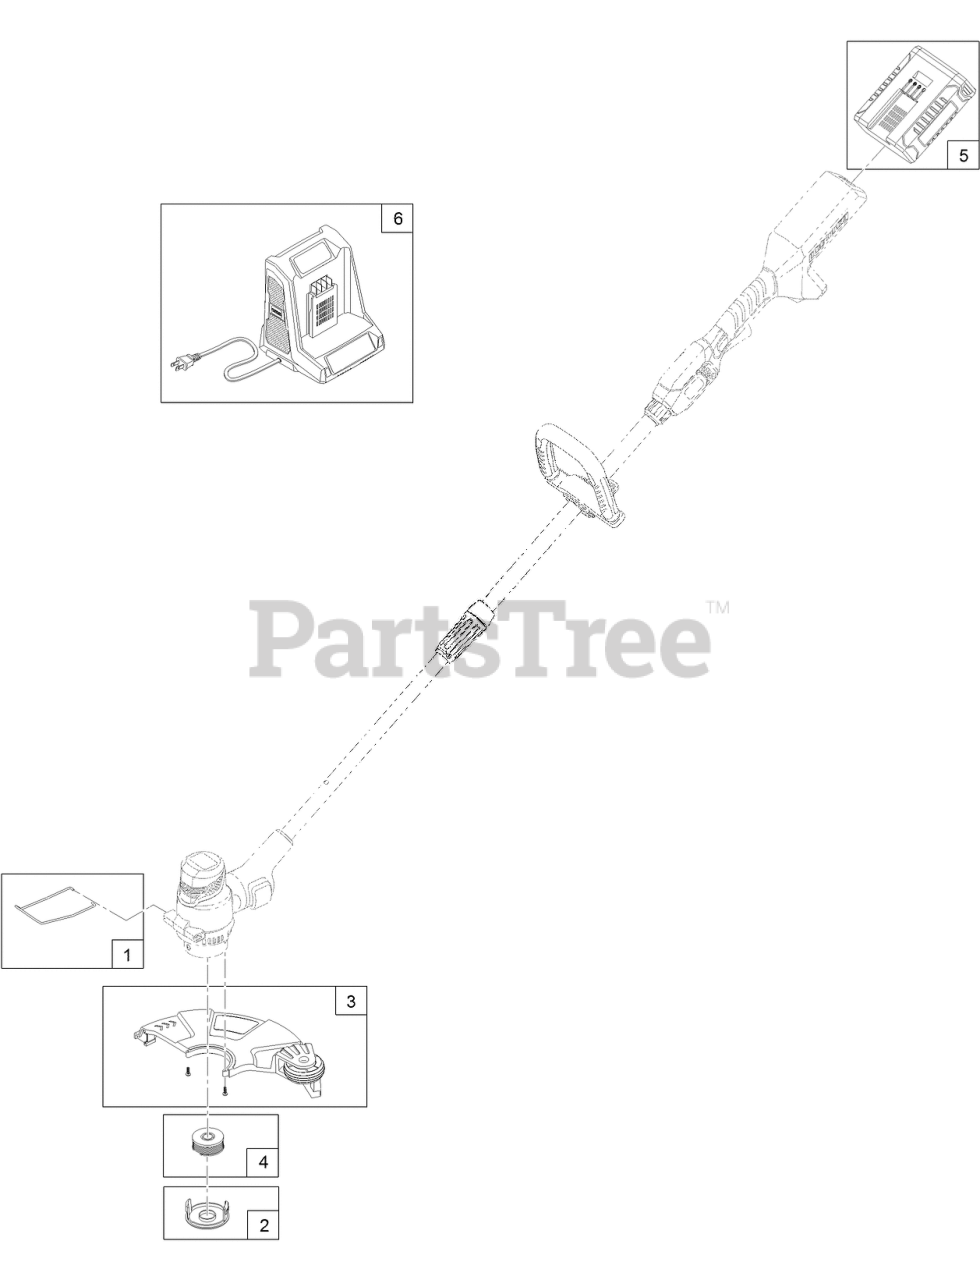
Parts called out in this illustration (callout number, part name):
1	CLIP-WIRE, GUIDE
2	CAP-RETAINER, SPOOL
3	GRASS SHIELD ASM
4	SINGLE LINE SPOOLS (3-PACK)
5	BATTERY-40V MAX
6	CHARGER-40V MAX
